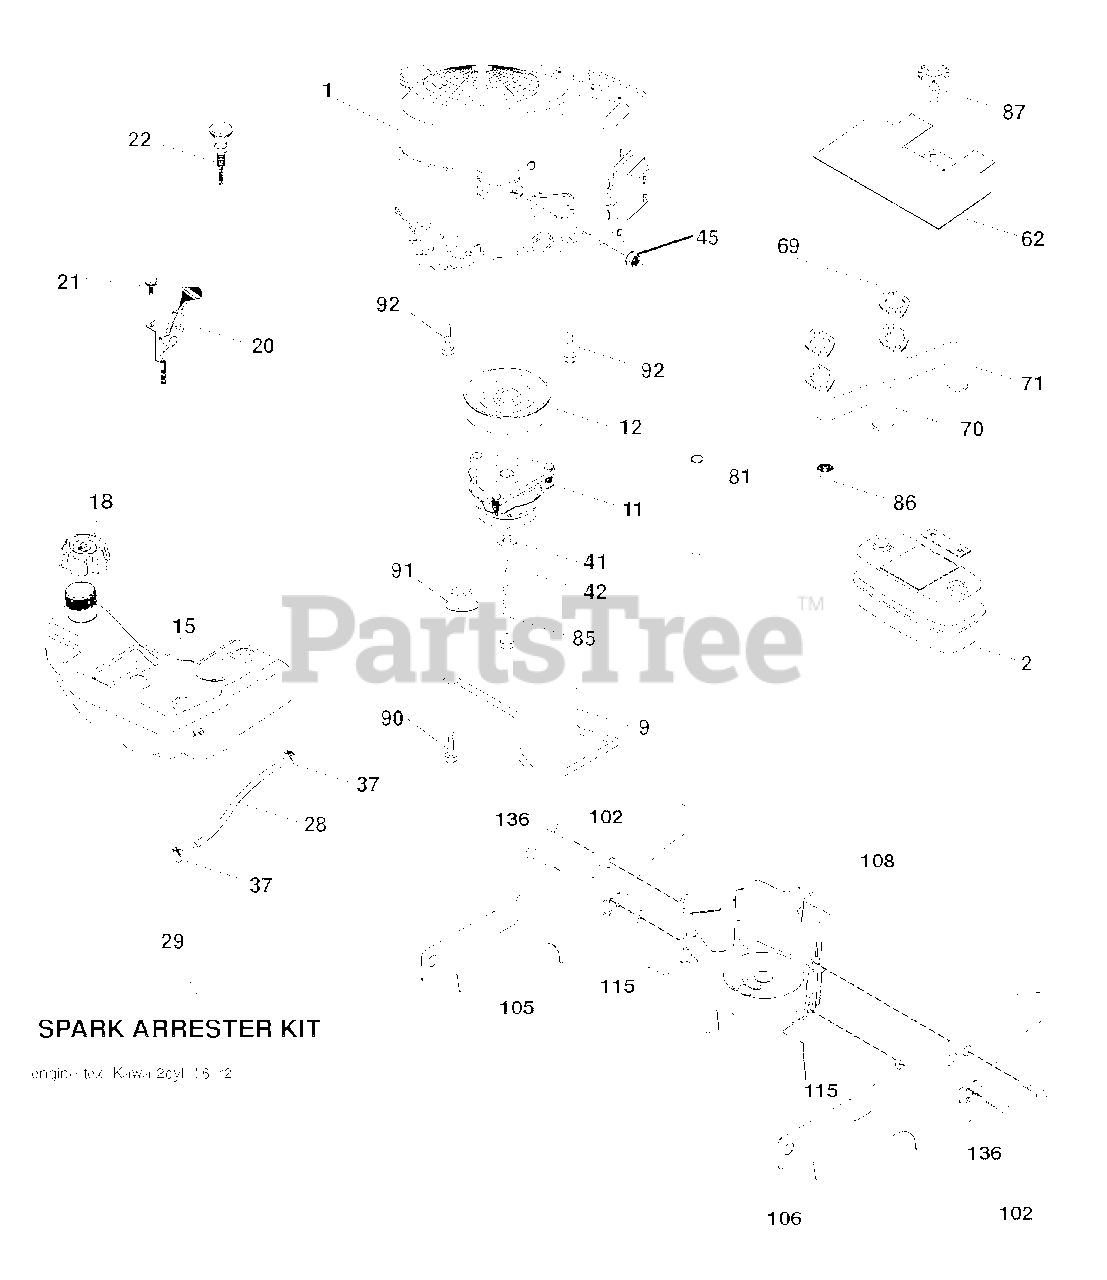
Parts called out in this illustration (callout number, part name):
2	MUFFLER.ASM.TWN.EXTNDED.DFLCTR
9	KEEPER.BELT.ENGINE.4.2
11	RB.CLUTCH.OGURA.4.4.PD
12	PULLEY.ENGINE.TUFFTORQ
15	TANK.FUEL.4GAL
18	CAP.FL.R.3'N/CARB.H.CROWN.498
20	CONTROL.THROTTLE.COBRA.BLACK
21	SCREW.#10 X 0.750.BOS
22	CONTROL.CHOKE.ERGO.PUSH-IN.BLA
28	REPL BY 532 00 85-43
29	KIT.SPARK ARRESTOR 794945 B&S
37	HOSE CLAMP
42	LOCKWASHER
45	NUT
62	SHIELD.HEAT.MUFFLER
70	TUBE.EXHAUST.LH.FR961/FR730
71	TUBE.EXHAUST.RH.FR961/FR730
81	TUBE, DRAIN OIL ASM.
85	BOLT HEX 7/16-20X4-1/4"
86	NUT.HEX.FLANGE.TOPLOCK
87	BOLT, 5/16-18 X 1 3/4
90	SCREW 3/8-16X1
91	BUSHING.1.375OD
92	SCREW 3/8-16X1
102	SCREW
105	SHIELD.SIDE.LH.3842"TEX FRENCH
106	SHIELD.SIDE.RH.3842"TEX FRENCH
108	ENGINE COVER
115	PALNUT 1/4
136	SCREW.1/4-20X5/8
